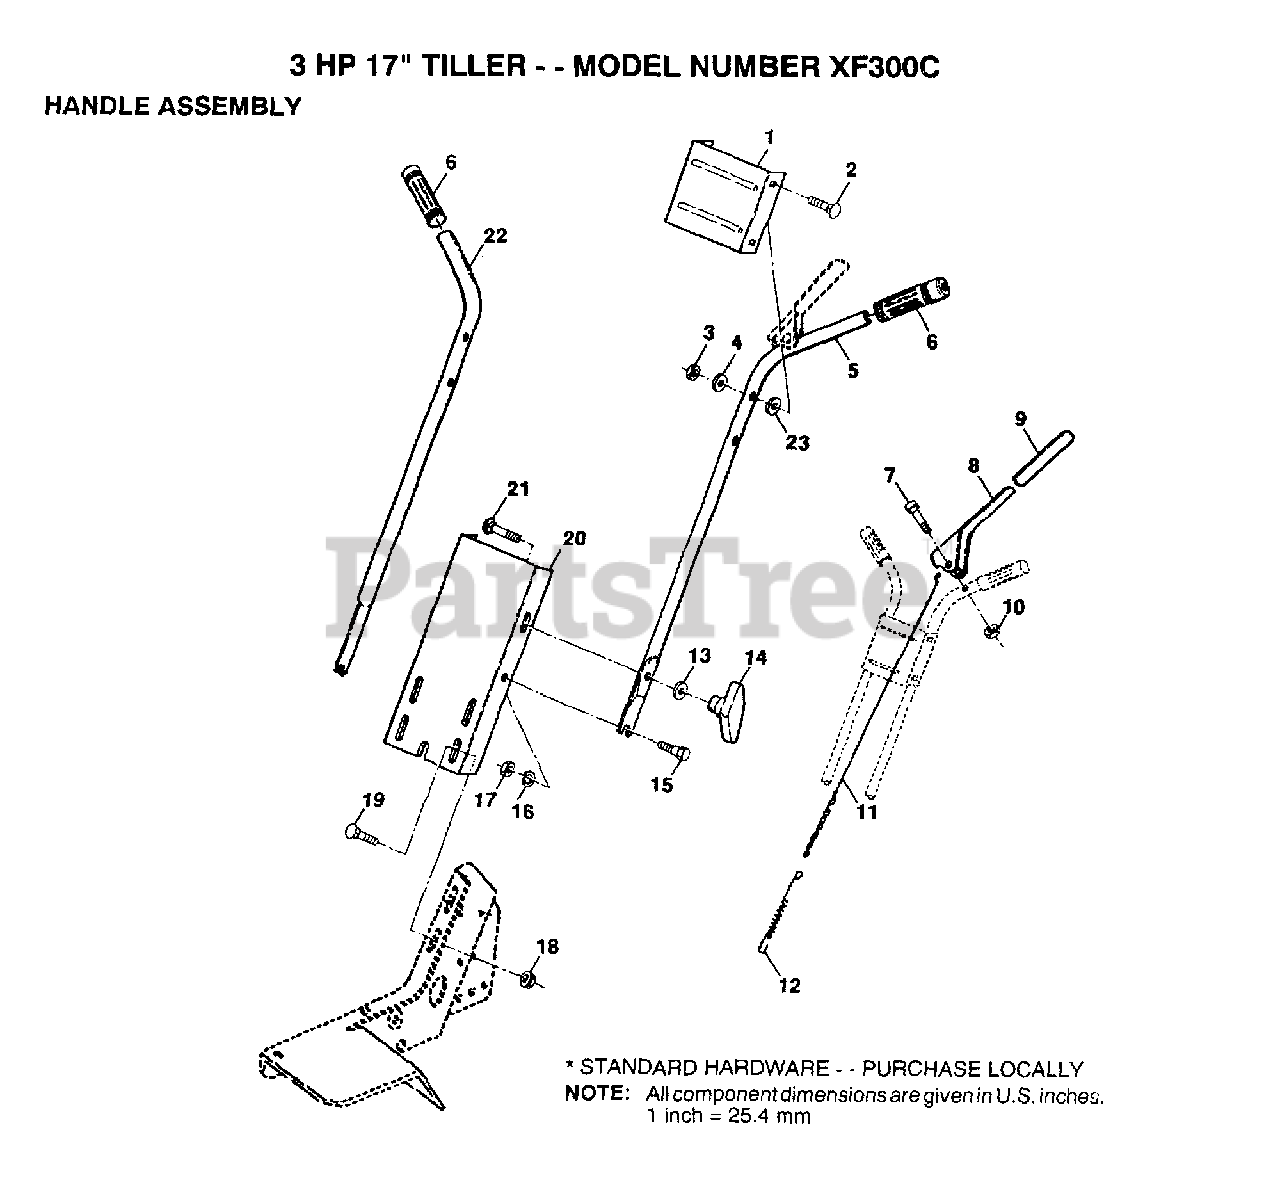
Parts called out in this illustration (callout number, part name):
1	PANEL.CONTROL.
2	BOLT
4	WASHER
7	BOLT.HEX.5/16-1.5
9	GRIP T
12	SPRING EXT TI
13	WASHER
14	KNOB HANDLE
16	LOCKWASHER
17	NUT.HEX.5/16-18
18	NUT
19	BOLT
21	BOLT
23	WASHER
